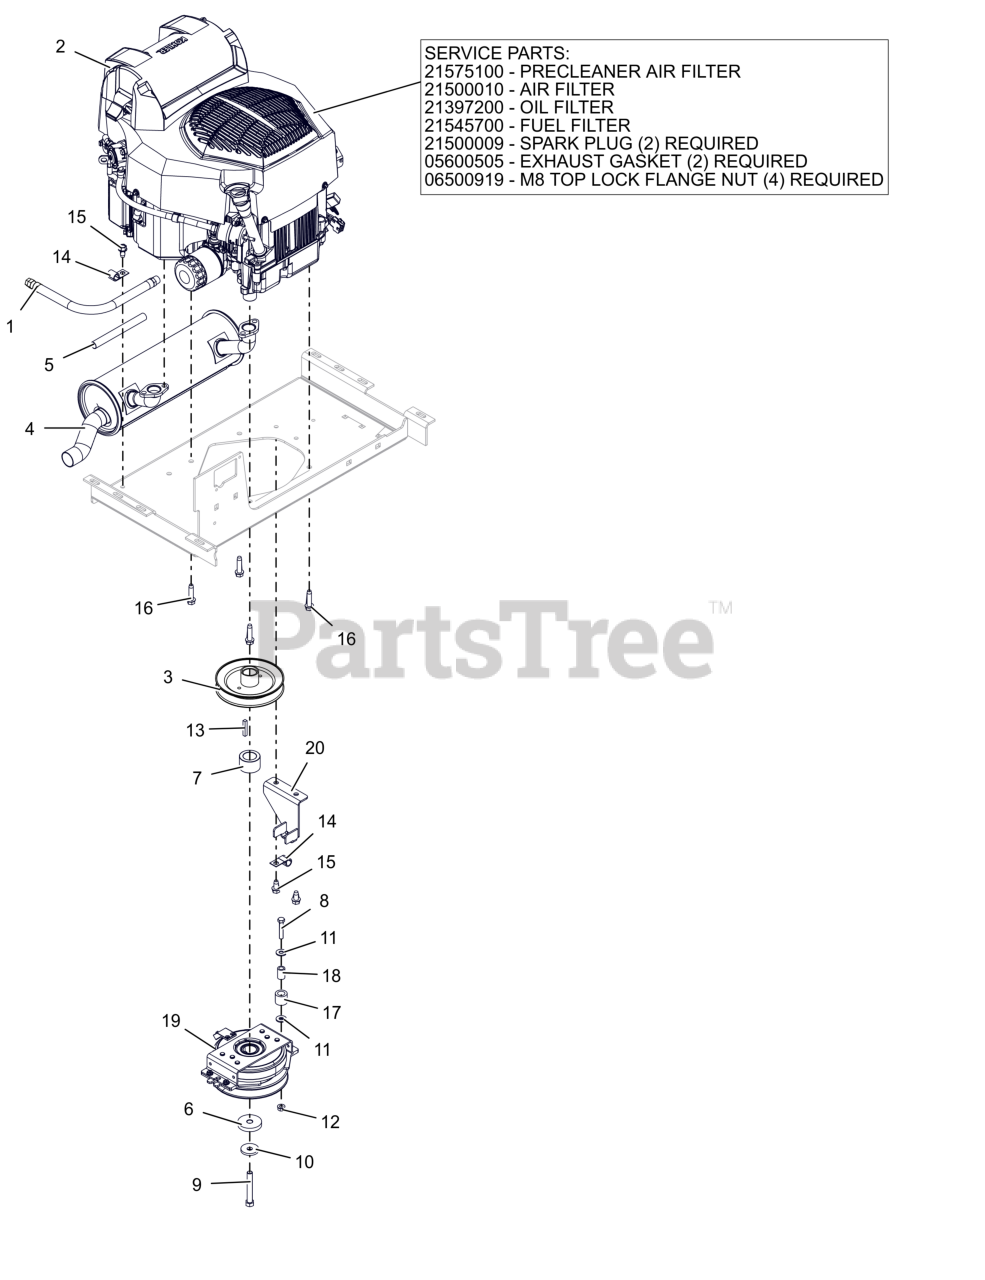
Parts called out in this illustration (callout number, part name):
1	HOSE, OIL DRAIN
2	ENGINE, KOHLER ZT740 CONFIDANT
2	PRECLEANER AIR FILTER
2	AIR CLEANER, KOHLER CONFIDANT
2	FILTER, OIL - KOH CV20
2	FILTER-FUEL KOHLER COURAGE PRO
2	PLUG, SPARK KOHLER
2	GASKET, MUFFLER KOHLER TWIN
2	NUT-LK-TOP-FLG M8 ZCC
3	WLDMT, TRANSAXLE DRIVE PULLEY
4	MUFFLER, ZT730/ZT740
5	SLEEVE, THERMAL 6"
6	SPACER, .474/.459X2.00X.350
7	SPCR, 1.125 x 1.750 x 1.147
8	BLT, HEX .31-18X1.75 G5 ZCC
9	BLT, HEX 0.4375-20X3 G8 ZCC NT
10	WASHER, 7/16" SPRING DISK
11	WSHR,FLT .375X.875X.083 ZCC
12	NUT,LK-CTR-FLG .31-18 GF ZCC
13	KEY-SQ .25 X 1.50 X .25 SAE
15	SCR,TAP .375-16X.75 HWH TR ZCC
16	SCR-TAP .38-16X1.50 HWH ZCC
17	BUMPER,RUBBER .62X1.0X.88 LG
18	BUSH.,S.391X.622X.950 ST
19	CLUTCH- OGURA GT2.75-DC03(D)
20	BRKT- CLUTCH STOP - BLACK
